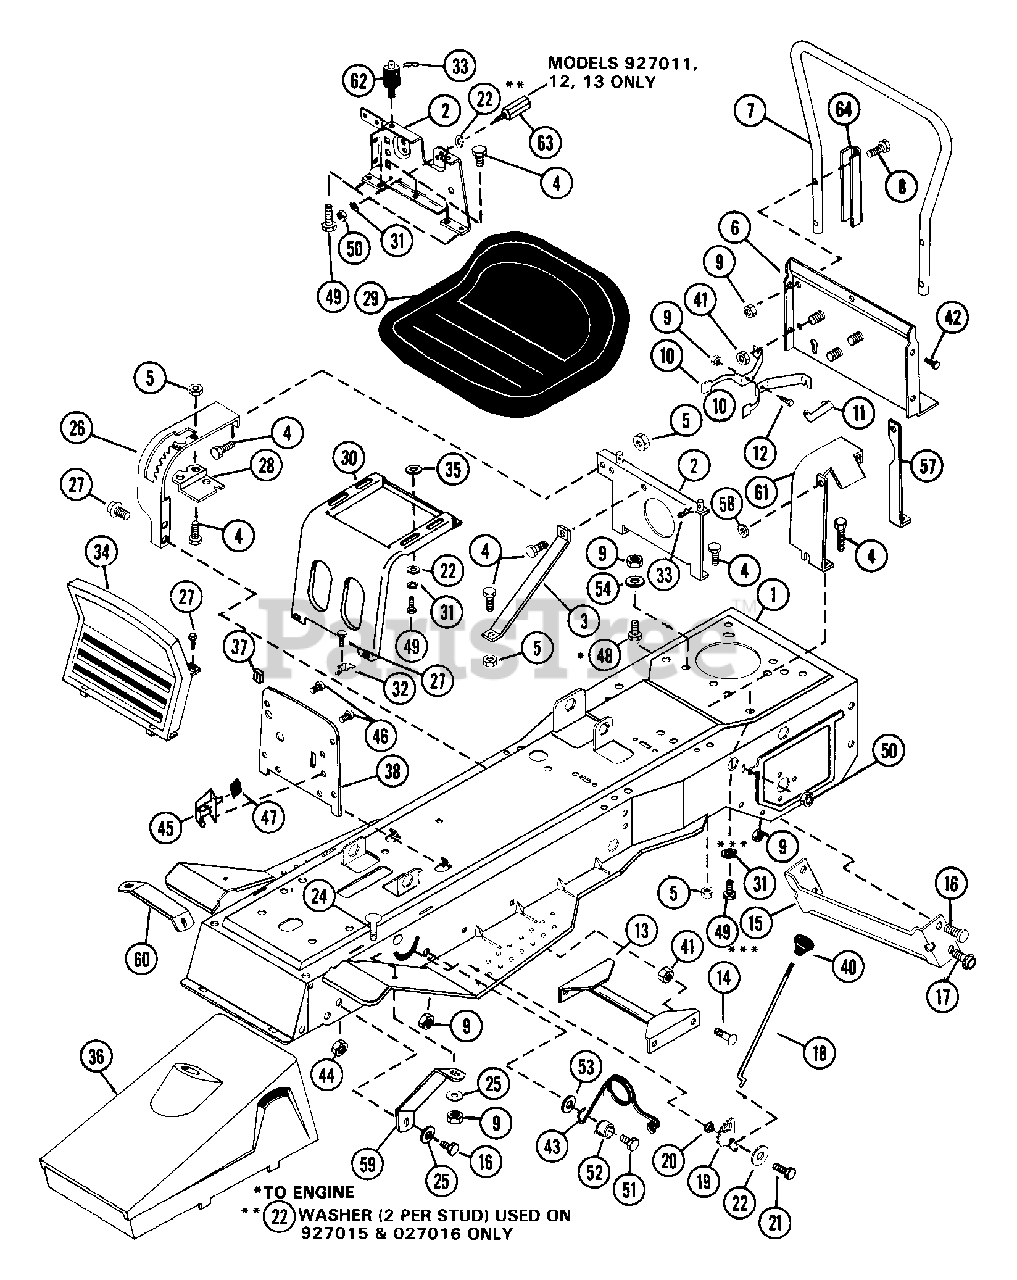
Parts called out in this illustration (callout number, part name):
1	FRAME
2	SEAT LEG
3	BRACE
4	BLT-HEX .25-20X.50 PL GR2
5	NUT-LK-CTR .250-20 PL
6	BACK COVER
7	TUBE
8	BLT-HEX .31-18X1.50 PL GR2
9	NUT-LK .312-18 GR A PL
10	BELT FINGER
11	BELT FINGER BRACE
12	BLT-HEX .31-18X.75 PL GR2
13	FRAME BRACE
14	BLT-RDHDSQNK .312-18X.62SHTPL
15	FRAME BRACE
16	BLT-HEX .31-18X.63 PL GR 2
17	SCR-TAP .312-18X1.50 HWH PL TR
18	PARKING BRAKE ROD
19	BRAKE LATCH
20	SPACER -SHLD .344X.500X.469
21	BLT-HEX .31-18X1.00 PL GR 2
22	WSHR-FL-STL .38X.875X.083 PL
24	BLT-RDHDSQNK .31-18X.75 GR5 PL
25	WSHR-FL-STL .323X.625X.062 PL
26	QUADRANT
27	BLT-SERHFWH .25-20X.50 PL
28	BRACKET NEUTRAL SWITCH
29	SEAT
30	SEAT BRACKET
31	WSHR-LK .312X.097 PL HVY
33	PIN-HAIR INT .08X.18X1.18
34	GRILLE INSERT & SHELL ASSEMBLY
35	WSHR-FL-STL .390X.750X.125 PL
37	PLASTIC GROMMET
38	DASH PANEL W/SILK SCREEN
39	SCR-TAP 10-24X.375 CRPH 1A
41	NUT-FLG. .312-18 PL
42	BLT-SERHFWH .31-18X.50 PL
43	SG-TORS .125X1.0X1.75
44	NUT-LK-TWIN .312-18 PL
45	THROTTLE CONTROL
46	SCR-TAP 10-12X.50 CRPH PL A BL
48	BLT-HEX .31-18X1.25 PL GR2
49	BLT-HEX .31-18X.75 PL GR5
50	NUT-HEX .312-18
51	BLT-HEX .31-18X.63 PL GR 2
52	SPACER BUSHING .5 X .32 X .163
53	WSHR-FL-STL .344X1.125X.063PL
54	WSHR-FL-STL .328X.875X.062 PL
56	NUT-LK-CTR .250-20 PL
58	GROMMET, .31 ID
59	FENDER BRACE
60	FENDER BRACE, R.H.
62	ISOLATION MOUNT
63	STUD SPACER
64	BRACE
